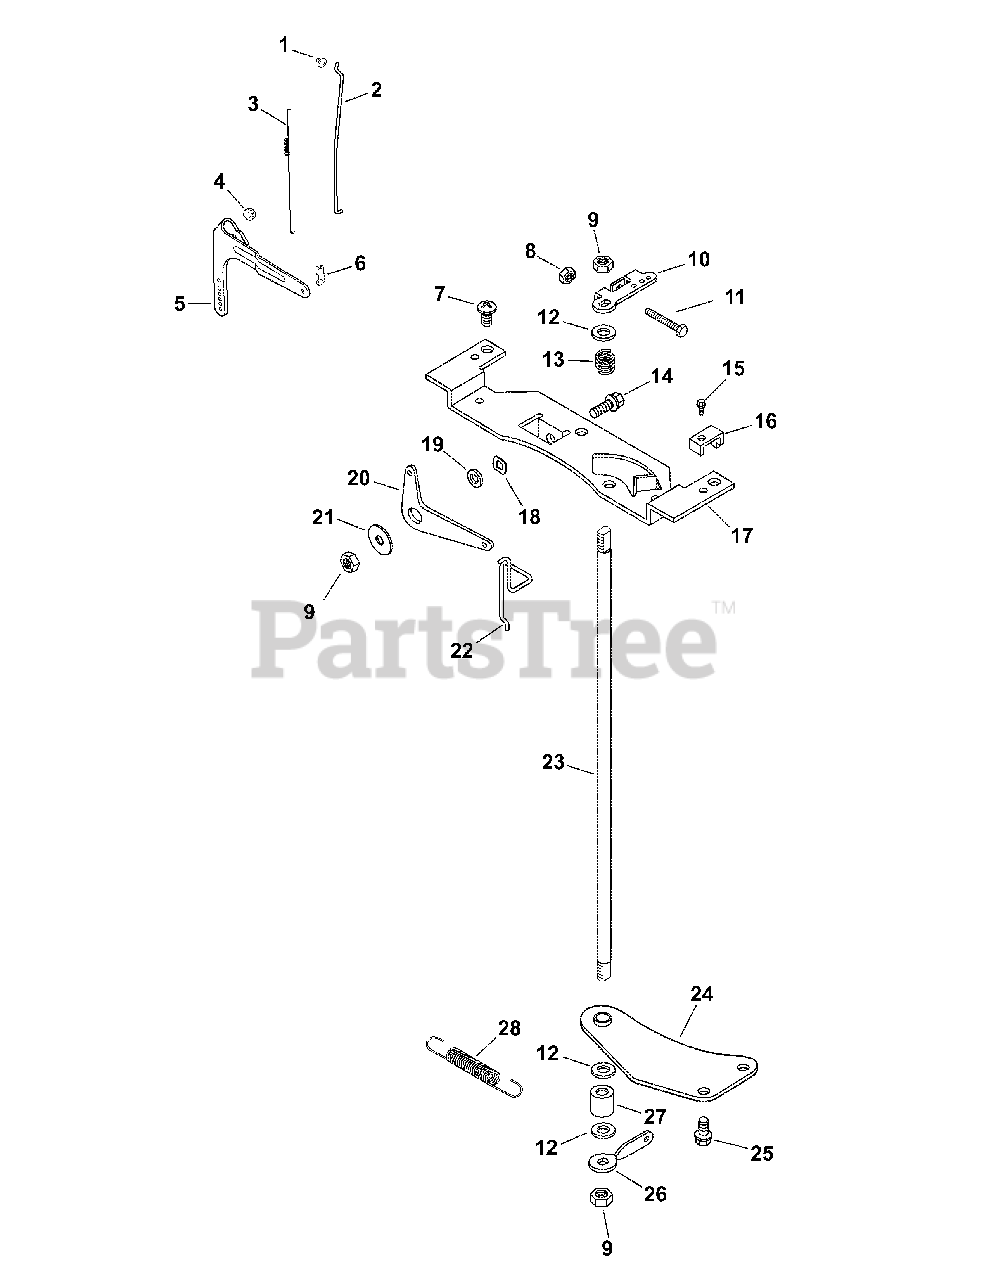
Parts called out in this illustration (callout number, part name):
1	Bolt, Rd Hd Sq Neck M6 x 1.0 x 25
2	Linkage, Throttle
3	Spring, Linkage
4	Nut, FLG M6 x 1.0
5	Lever, Governor
6	Bushing, Throttle Linkage
7	Screw, Phl Hd 11-16 x 3/4"
8	Nut, M4 x 0.7
9	Nut, Lock M6 x 1.0
10	Lever, Throttle Control
11	Screw, Cap M4 x 0.7 x 30
12	Washer, Flat 1/4"
13	Spring, Throttle Shaft
14	Screw, Flg M6x1.0x16
15	Screw, Flg Thd Frm M5 x 0.8 x 16
16	Clamp, Cable
17	Bracket, Control
18	Washer, Spring 3/8"
21	Washer, Flat 1/4"
22	Linkage, Choke
23	Shaft, Throttle
24	Bracket, Throttle Shaft
25	Screw, Flg Thd Frm M6 x 1.0 x16
26	Lever, Throttle Control
28	Spring, Governor
